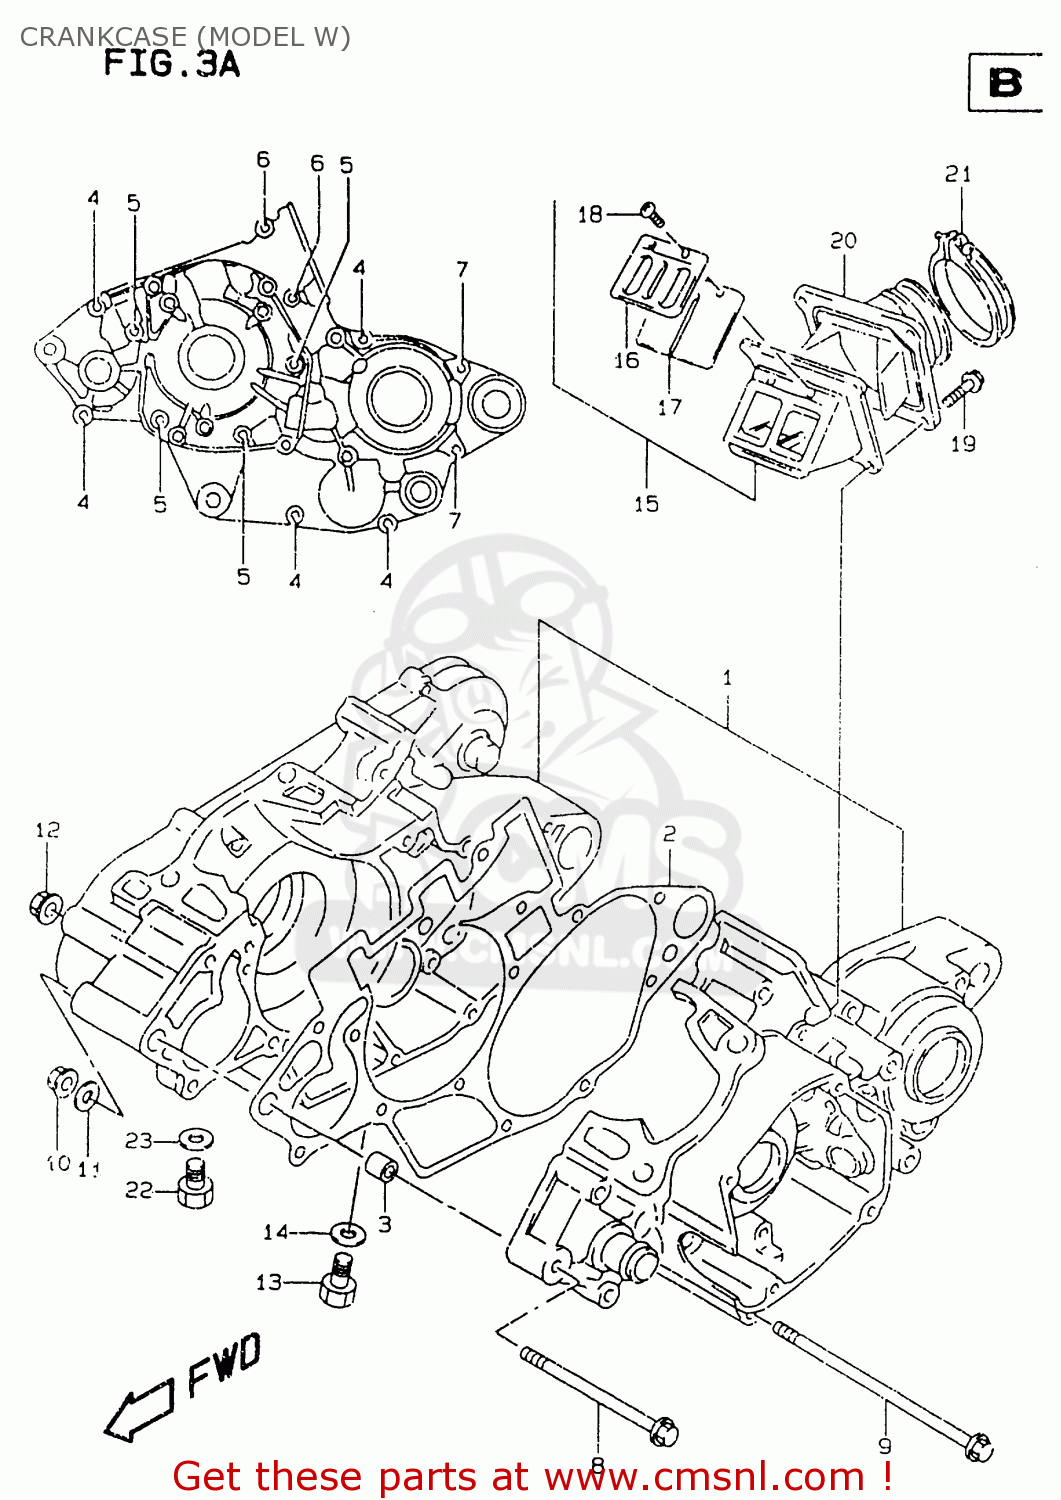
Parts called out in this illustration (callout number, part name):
1	CRANKCASE SET
2	GASKET,CRANKCASE
3	PIN(13X10.4X20)
4	BOLT
5	BOLT
6	BOLT
7	BOLT
8	BOLT(8X88)
9	BOLT(10X130)
10	NUT
11	WASHER
12	NUT
13	Bolt
14	GASKET(12.1X16.2X3.7) (NAS)
15	VALVE ASSY,REED
16	STOPPER,REED VALVE
17	VALVE,REED
18	SCREW
19	SCREW
20	PIPE,INTAKE
21	CLAMP
22	BOLT,DRAIN
23	GASKET 8.2X14X1 (NAS)
